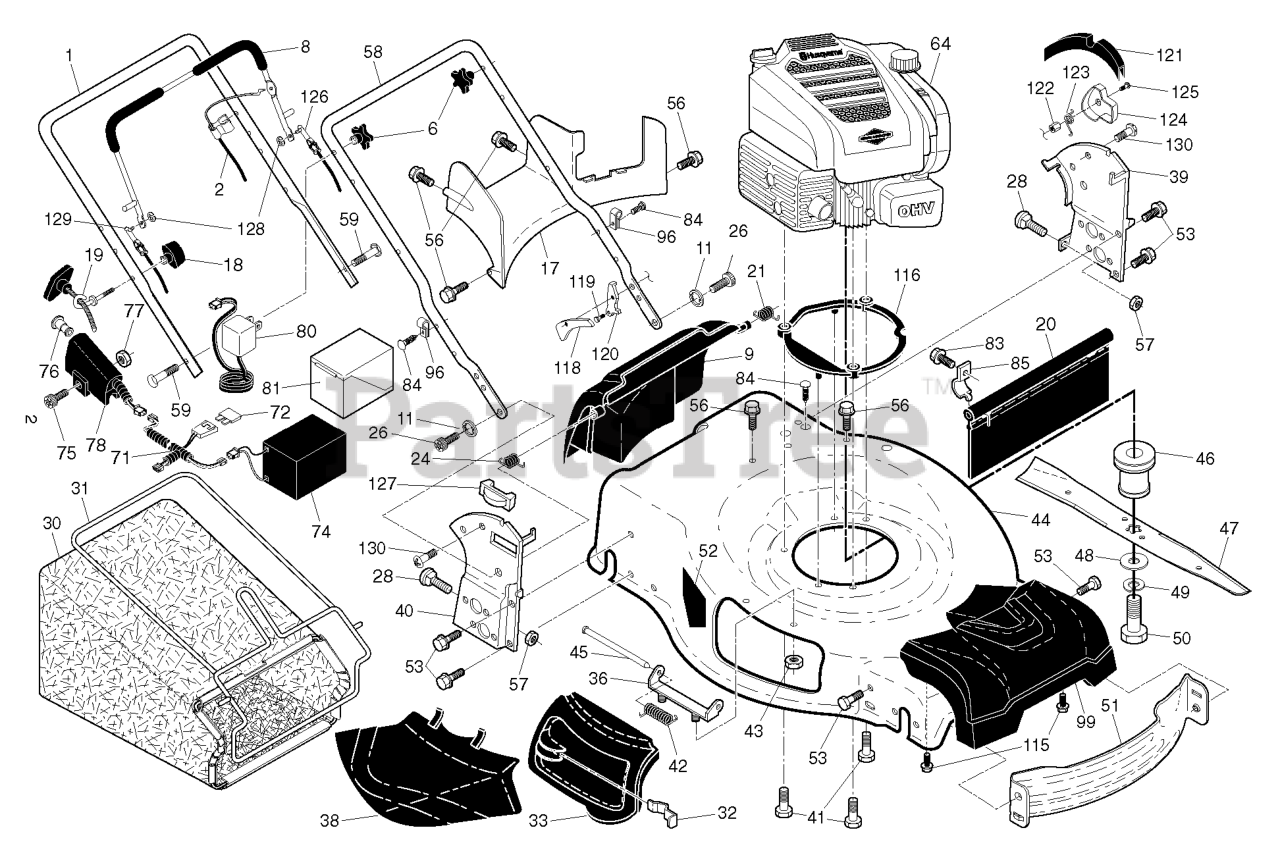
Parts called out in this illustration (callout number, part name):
1	HANDLE.UPPER.3.POS.BS.AW2.GREY
2	CABLE.MZR.RGD.22.B&S/HON.ERGO
6	KNOB.HANDLE.PLASTIC.STAR.BLACK
8	BAIL.CONTROL.MZR.ERGO.EZS.O/B
9	DOOR.REAR.ASM.22+GEN.FG/RG.498
11	E-RING.12MM.SHAFT
17	BAFFLE.REAR.22+RGD.AWD.PLASTIC
18	T-KNOB.NEW ROPE GUIDE
19	GUIDE.ROPE.BLK.ZINC.CHROM
20	SKIRT.REAR.22PLUS.RGD.LW(2 2MC
21	SPRING.LH.BLACK
24	SPRING.RH.GRAY
26	SCREW,DOOR/HANDLE.PIVOT
28	BOLT.CARRIAGE.LN.5/16-18X.5/8
30	GBAG.B561029EM.GRY/SILV
31	FRAME.GBAG.22+.BLK
32	LATCH.DOOR.ZINC
33	DOOR.MULCH.22 PLUS.HUSQ.GREY
36	BRACKET.ASM.HINGE.21.FWGD.
38	DEFLECTOR.CLIPPING.22.BLACK
39	BRACKET.ASM.HANDLE.LT.22+.498
40	BRACKET.ASM.HANDLE.RT.22+.498
42	SPRING.TORSION
43	NUT.FLANGE.1-4-20-SERR
44	KIT.HSG.22+AWD.MC.WO.668.TRI
45	ROD.HINGE.21
46	ADAPTER.BLADE.25M.B&S.AWD
47	BLADE REAPER, 22 IN RUST
48	WASHER,HARDEN
49	LOCKWASHER
50	BOLT.BLADE
51	BAFFLE.FRONT.22.PLUS
52	DANGER DECAL
53	BOLT.5/16HEX.WHS.HD
56	SCREW.HX.13X.750
57	NUT.FLANGE.5/16
58	HANDLE.LOWER.22+EZS.498
59	BOLT, HANDLE 5/16-18X1.75
71	HARNESS.WIRE.ES.RGD.BUTTON.CON
74	BATTERY.12V.22+RWGD
75	BOLT.M6-1X40.T30
76	BUTTON.KEY.CYLINDER.BLACK
77	NUT.M6-1 NYLOC
78	STARTER.ASM.PUSH.BUTTON
80	CHARGER.BATT.12V LEAD-ACID.DOM
81	COVER.BATTERY.BOX 22+RDG.BLK
83	TAPPING SCREW
84	FASTENER.PUSH.O.250X0.783
85	BRACKET.SKIRT.22+.BZP
96	CLIP.CABLE.BLK
99	COVER.ASSEMBLY.FRONT.22+AWD
115	SCREW.SHOULDER.5/16X1.375
116	SPACER.AWD.B&S
118	COVER.INSIDE.LOWER.LT.EZS
119	BOLT.PAWL.M6
120	PAWL.ADJUSTMENT.EZS.LEFT
121	BRACKET.BAG.ASM.EZS.LH.BLK
122	NUT.PAWL.M6
123	SPRING.TORSION.PAWL ENG.LT
124	COVER.OUTSIDE.LOWER.EZS.LT
125	SCREW.TORX.PAN HEAD.M6-1
126	CABLE.MZR.EZS.LH.DSTR/ERGO
127	DOOR.REAR.LIFT.ASM EZS
128	E-RING.5/32.HD
129	CABLE.MZR.EZS.RH.ERGO.PB
130	SCREW.PAN.HEAD.#10
